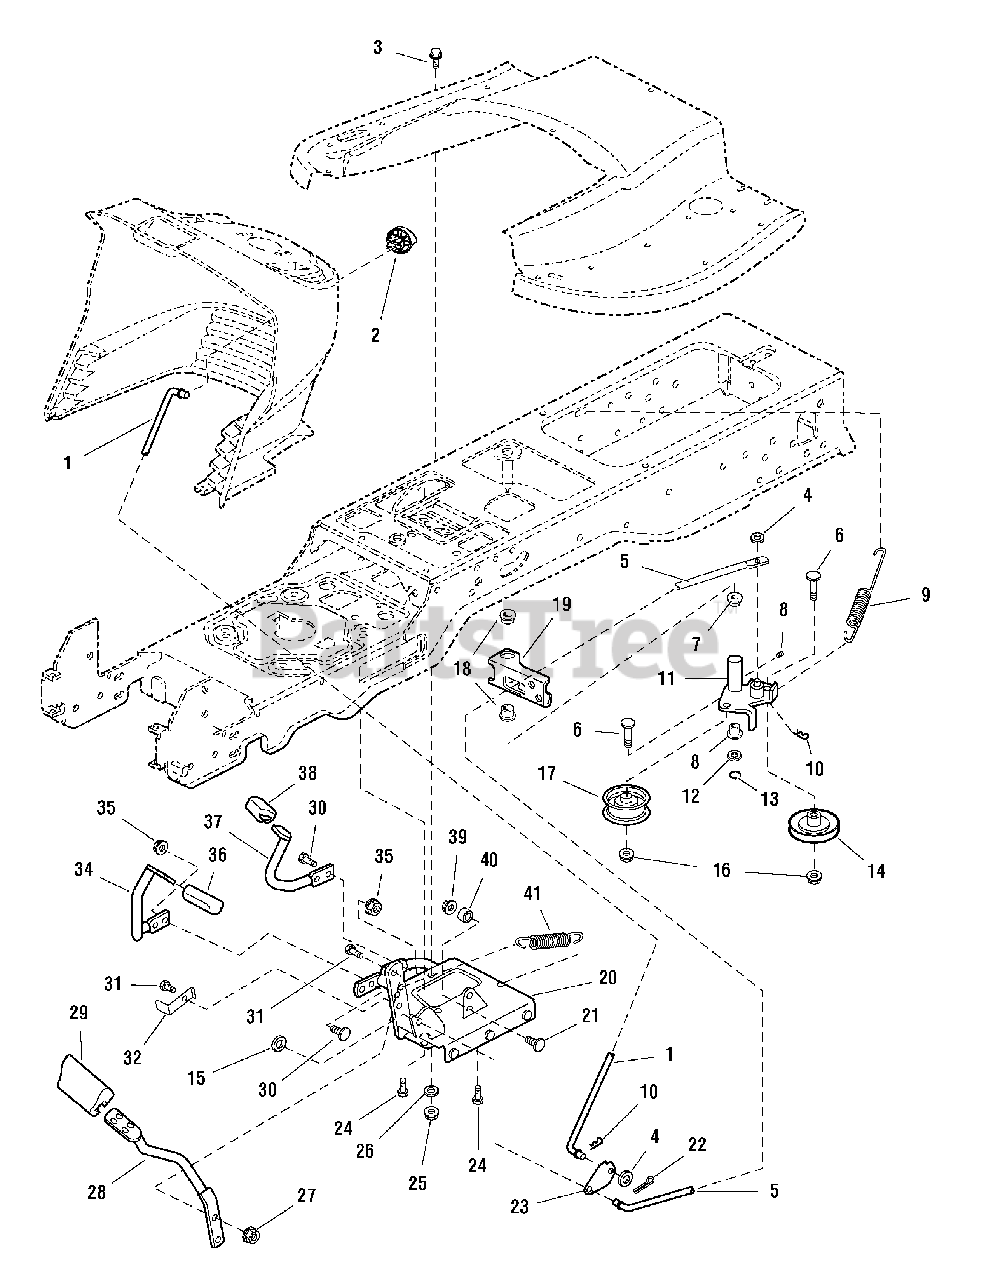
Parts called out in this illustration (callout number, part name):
1	ROD, Brake Lock
2	KNOB, Push On
3	SCREW, 5/16-18x0.750, GR5, WHIZ-LOCK, ZC
4	WASHER, 0.312 (0.34 ID X 0.75 OD X .06THK) BLK
5	ROD, Brake
6	BOLT-RD HD SH SQ NK 3/8-16X1.750 G5 BLK
7	BUSHING
8	FITTING, Lube 1/4 Drive
9	SPRING, Extension
10	HAIR PIN, .080 Wire x 1.19 LG x .25/.38 Dia
11	ARM & HUB ASSEMBLY, Idler
12	WASHER, Plain, 5/8 (Early models only)
13	RING, External (Klipring) for .625 Dia. Shaft
14	PULLEY, 3" OD x .378" ID x .75" WD, w/Bearing
15	WSHR,.406X.875X.083FLT,TYPE A,ZINC/CLEAR
16	NUT, Hex Lock Flange, 5/16 - 18 ESNA
17	USE-1721133, PULLEY, IDLER,FLAT, 2.75DIA
18	BUSHING, 1 x 1-1/8 x 5/8, Nylon
19	ARM, Brake
20	CONTROL ASSEMBLY, Foot Pedal
21	BOLT, Carriage, Short Neck, 1/4-20 x 1-1/4, G5
22	PIN, Cotter, 3/4, Black
23	LATCH, Brake
24	CAPSCREW, Hex Washer Head, Taptite, 5/16-18 x 3/4
25	NUT, Hex Lock ESNA Light, 5/16-18
26	WASHER-0.312(0.34IDX1.00ODX.13THK)BLK
27	NUT, Hex Flange Whiz-Lock, 5/16-18
28	PEDAL, Brake
29	PAD, Brake Pedal
30	BOLT, 5/16-18 x 7/8" Round Head Short Square Neck Carriage, GR5
31	CAPSCREW, Hex Head, 5/16-18 x 1 1/4
32	ACTUATOR, Switch 2.53" Long
34	PEDAL, Forward
35	NUT, Keps Lock, 5/16 - 18
36	PAD, Foot Pedal, Forward
37	PEDAL, Reverse
38	PAD, Foot Pedal, Reverse
39	NUT, Hex Lock, ESNA Light, 1/4-20
40	CAM, Roller, .686 OD, .253 ID, .575 LG
41	SPRING, Extension, 5/8 OD x 6-5/8 Long
